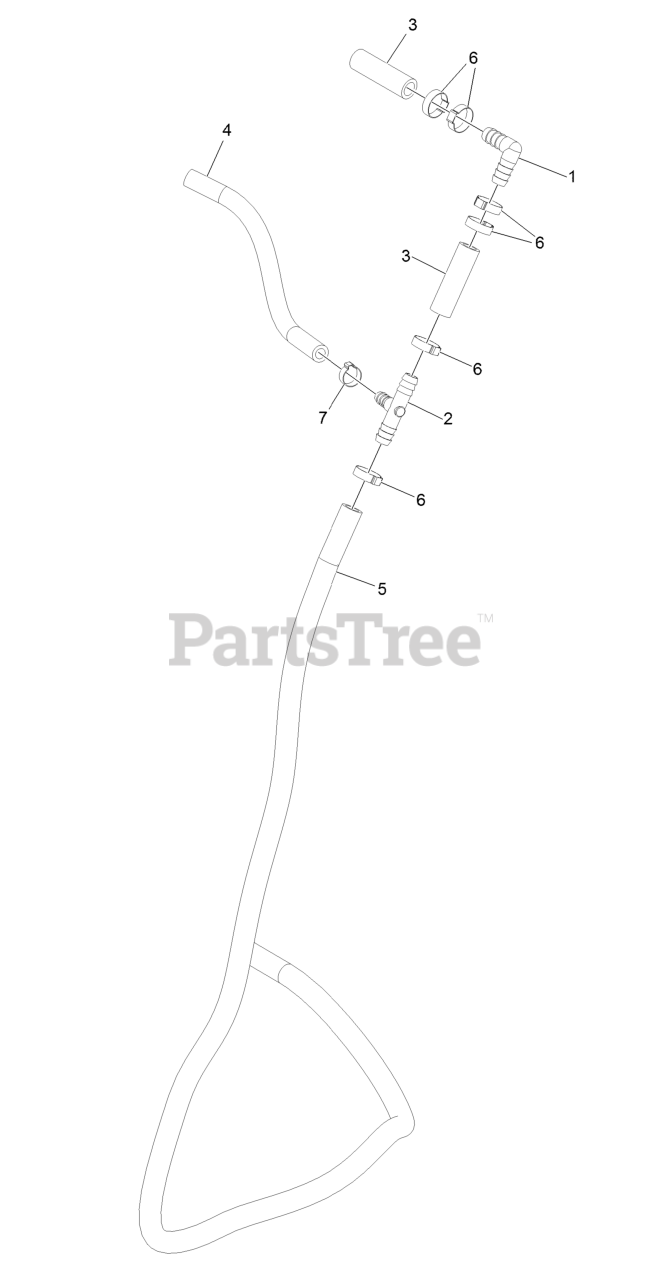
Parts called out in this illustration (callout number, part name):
1	Fitting-Elbow-90
2	Connector-Tee
3	Hose-Water
4	Hose-Water
5	Hose-Water
